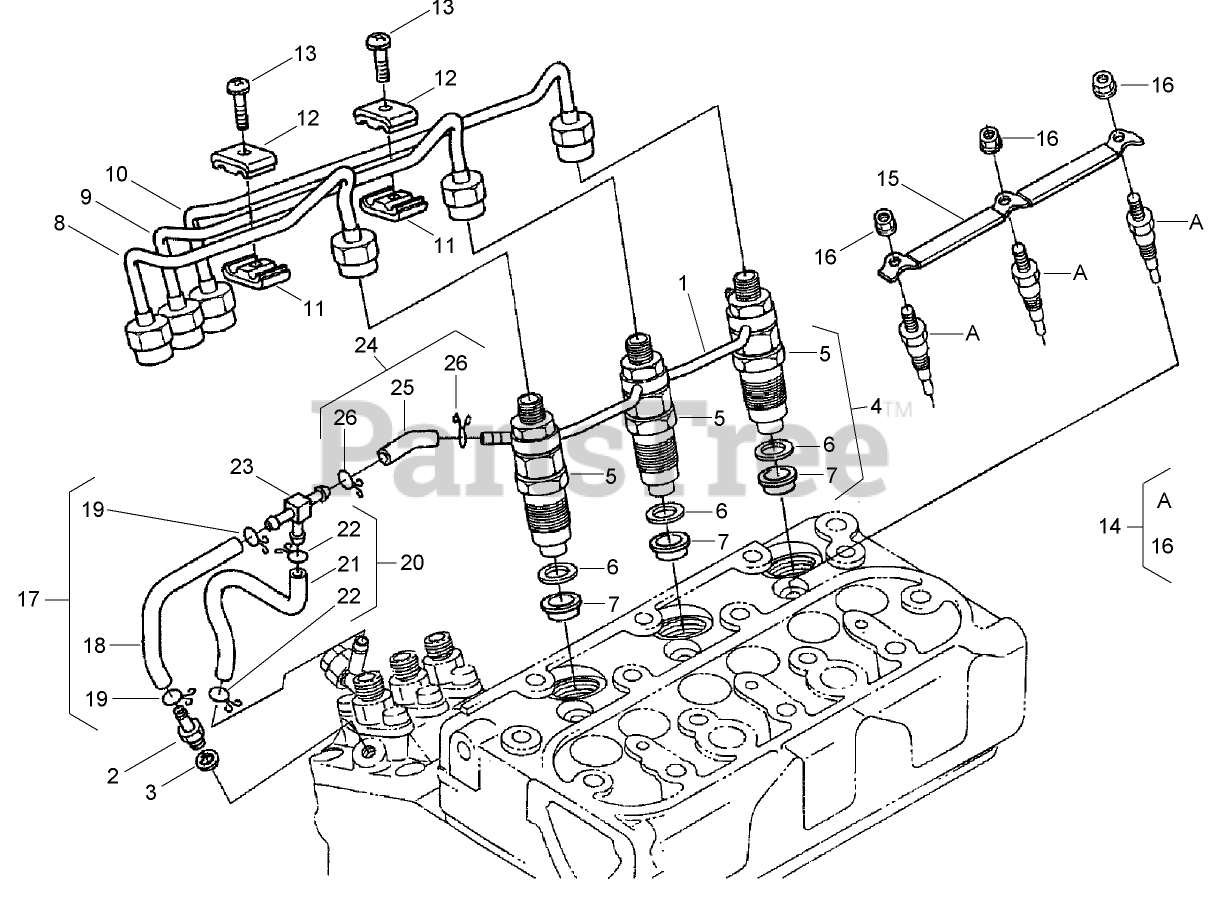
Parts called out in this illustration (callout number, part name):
1	OVER FLOW PIPE ASM
2	SCREW-BLEEDER, AIR
3	GASKET
4	NOZZLE HOLDER KIT
5	NOZZLE HOLDER ASM
6	GASKET
7	SEAL-HEAT
8	PIPE-INJECTION
9	PIPE-INJECTION
10	PIPE-INJECTION
11	CLAMP-PIPE
12	CLAMP-PIPE
13	SCREW (W/WASHER)
14	PLUG-GLOW
15	CORD-PLUG, GLOW
16	NUT-FLANGE
17	FUEL TUBE ASM
18	TUBE-FUEL
19	CLIP-PIPE
20	FUEL TUBE ASM
21	TUBE-FUEL
22	CLIP-PIPE
23	PIPE-JOINT, T
24	FUEL TUBE ASM
25	TUBE-FUEL
26	BAND-PIPE
